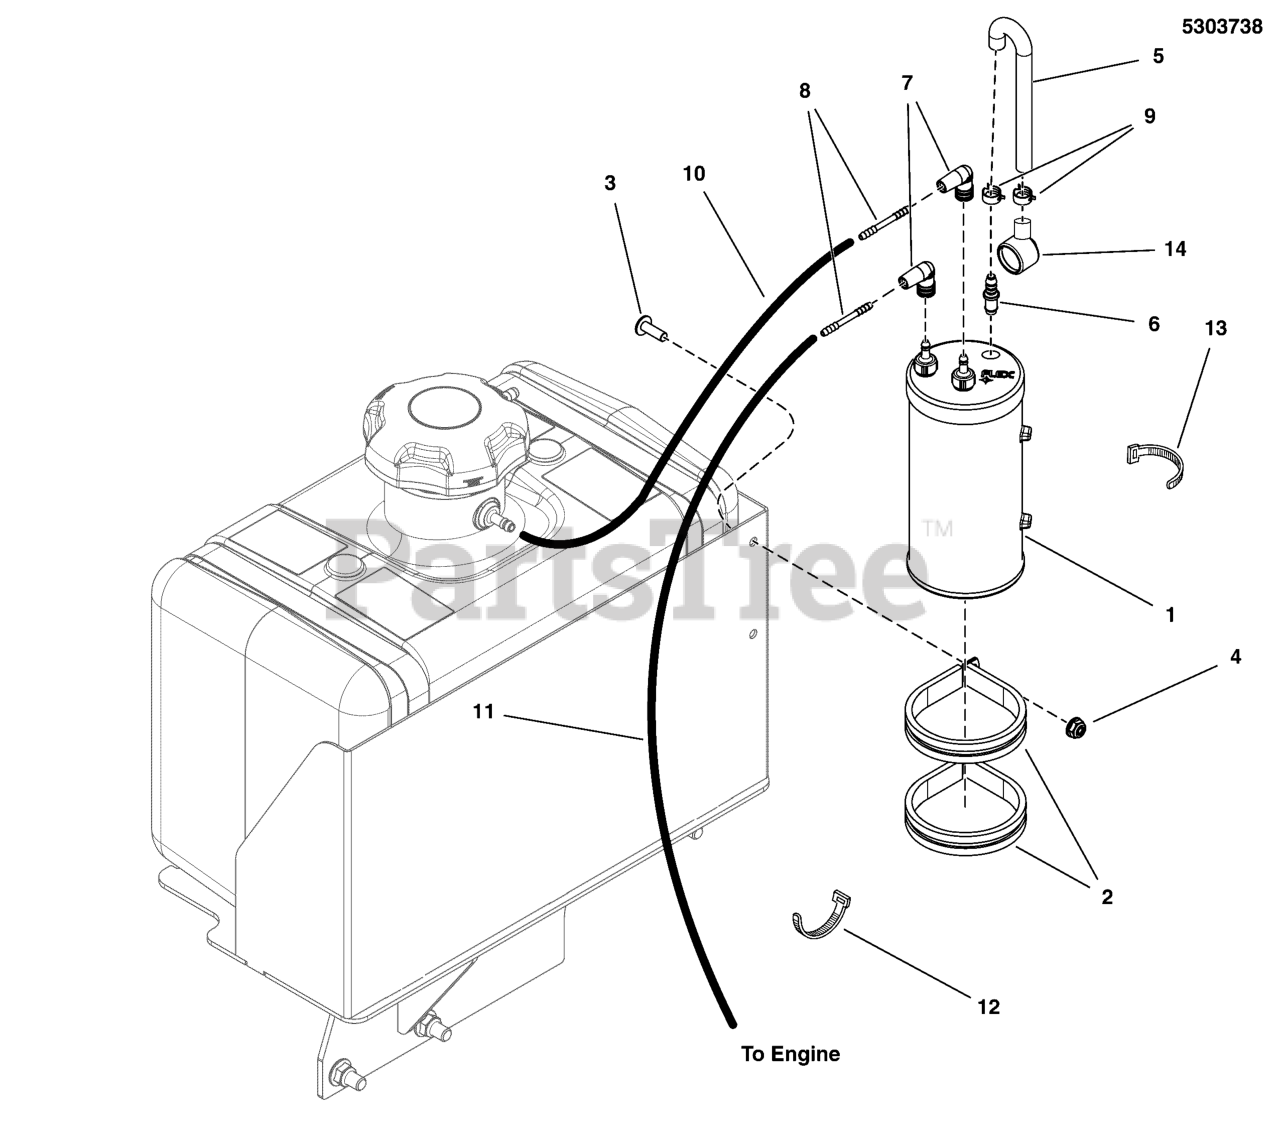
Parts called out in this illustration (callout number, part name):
1	CNSTR, CARB, 6 GAL
2	CLAMP, 3" ID, CUSHIONED, STAINLESS
4	NUT, 1/4-20 HEX NYLOCK FLANGE
5	HOSE, FORMED, EVAP CANISTER
6	FITTING, STRAIGHT, 10MMX10MM, PLASTIC
7	FITTING, 90 DEG, 3/16X3/16, SANTOPRENE
8	FITTING, STRAIGHT, 3/16X3/16, PLASTIC
9	CLAMP, HOSE
10	HOSE, VAPOR, 5MM ID, 8.00 LG
11	HOSE, VAPOR, 5MM ID, 24.00 LG
12	TIE,SELF-LOCKING, 6"
13	TIE, SELF-LOCKING, 15"
14	DUST FILTER, CANISTER (SV)
